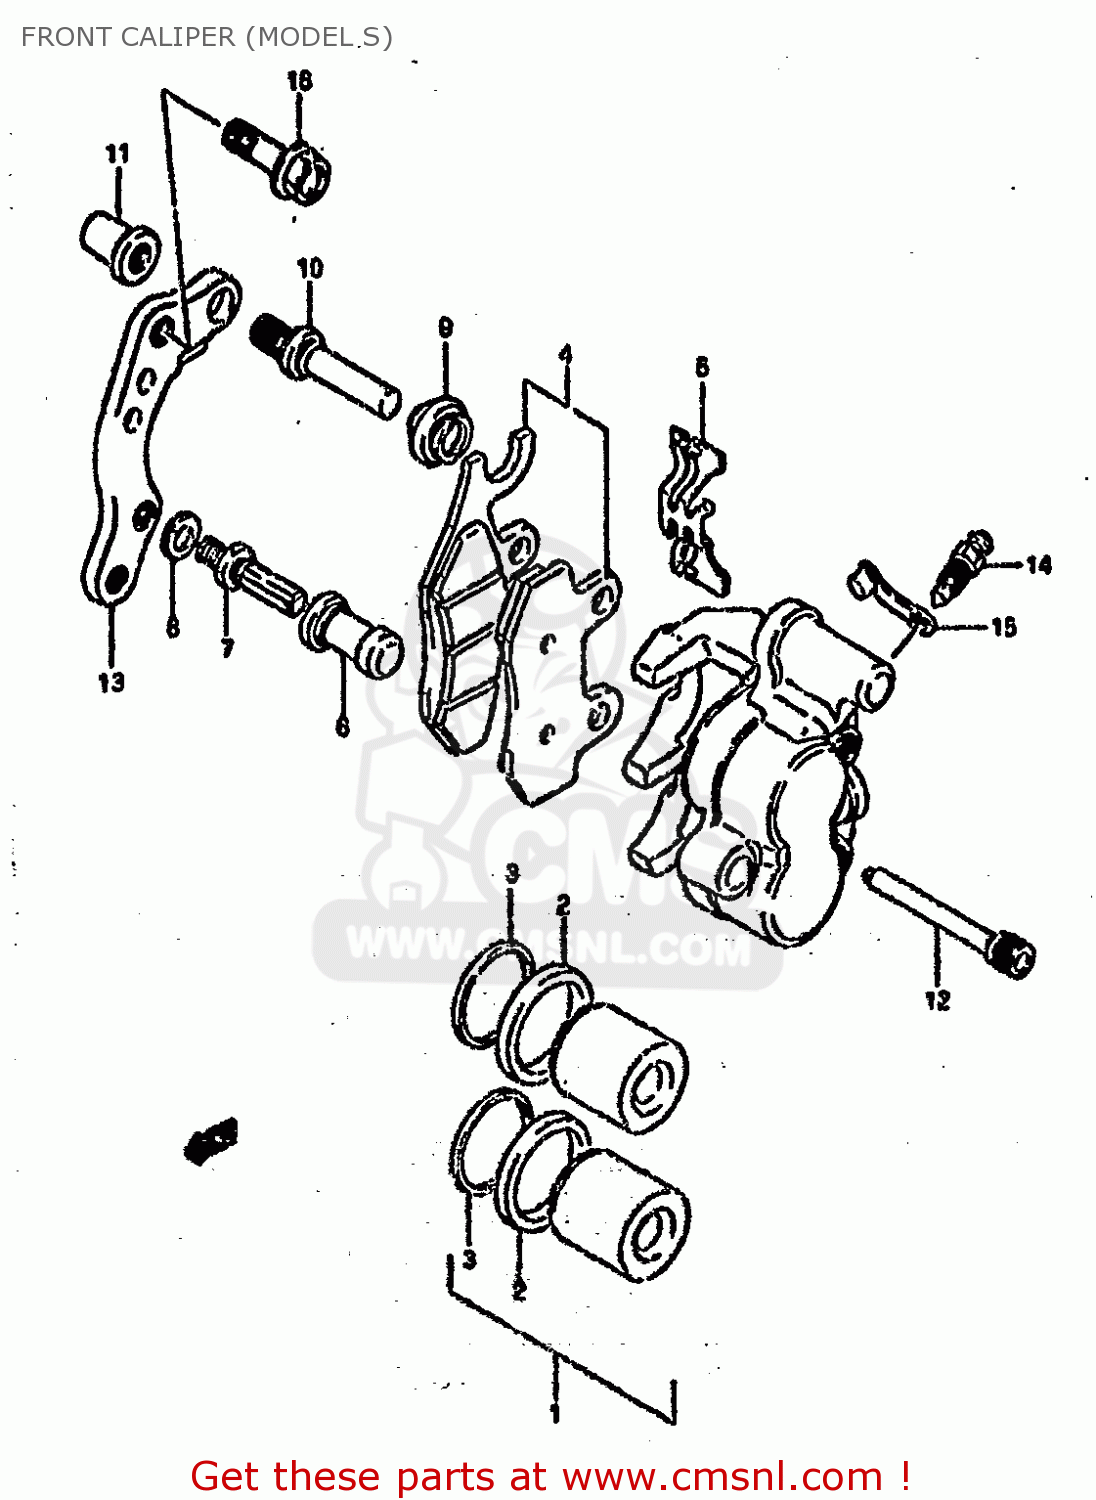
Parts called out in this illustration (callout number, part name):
1	PISTON SET
2	SEAL,PISTON
3	SEAL,DUST
4	PAD SET (NAS)
5	SPRING,PAD
6	BOOT
7	BOLT,PIN
8	WASHER
9	BOOT
10	PIN,SLIDE
11	NUT
12	PIN,HOLDER
13	BRACKET
14	BLEEDER
15	CAP,BLEEDER
16	BOLT,FRONT CALIPER
